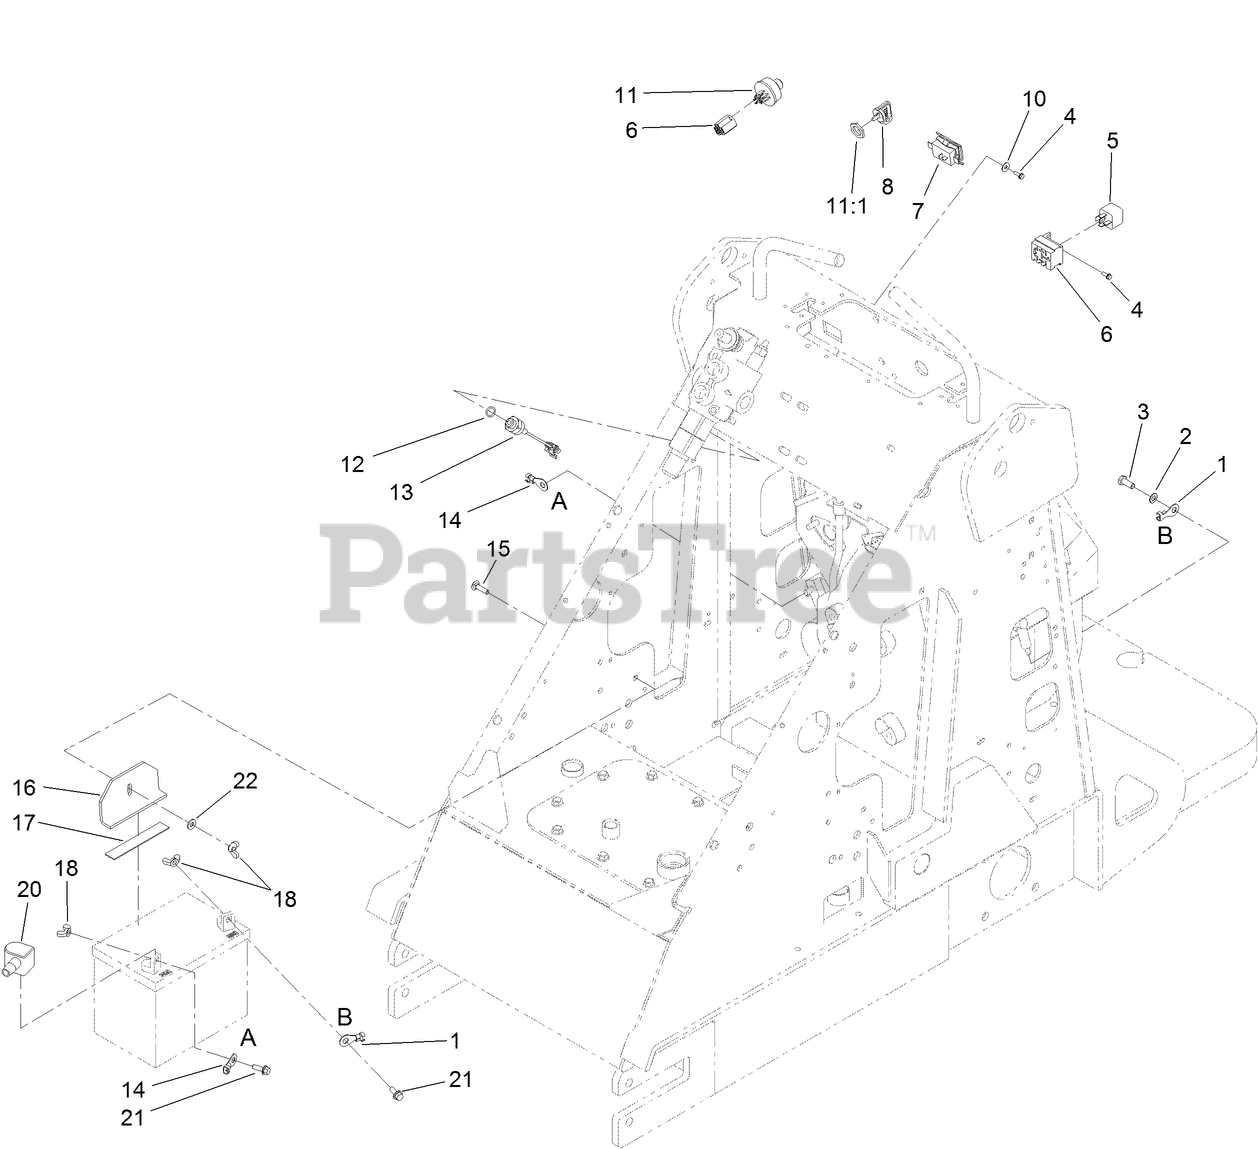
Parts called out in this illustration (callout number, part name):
1	CABLE-BLACK
2	WASHER-LOCK
3	SCREW-HH
4	SCREW-HWHTF
5	RELAY
6	HARNESS-WIRE
7	METER-HOUR
8	KEY-IGNITION
10	WASHER-PLAIN
11	KEY SWITCH ASM
12	O-RING
13	SWITCH-BALL
14	WIRE-21 INCH
15	SCREW-CARR
16	CLAMP-BATTERY
17	PAD-FOOTREST
18	NUT-WING
20	BOOT-TERMINAL, RED
21	SCREW-HHF
22	WASHER-FLAT
